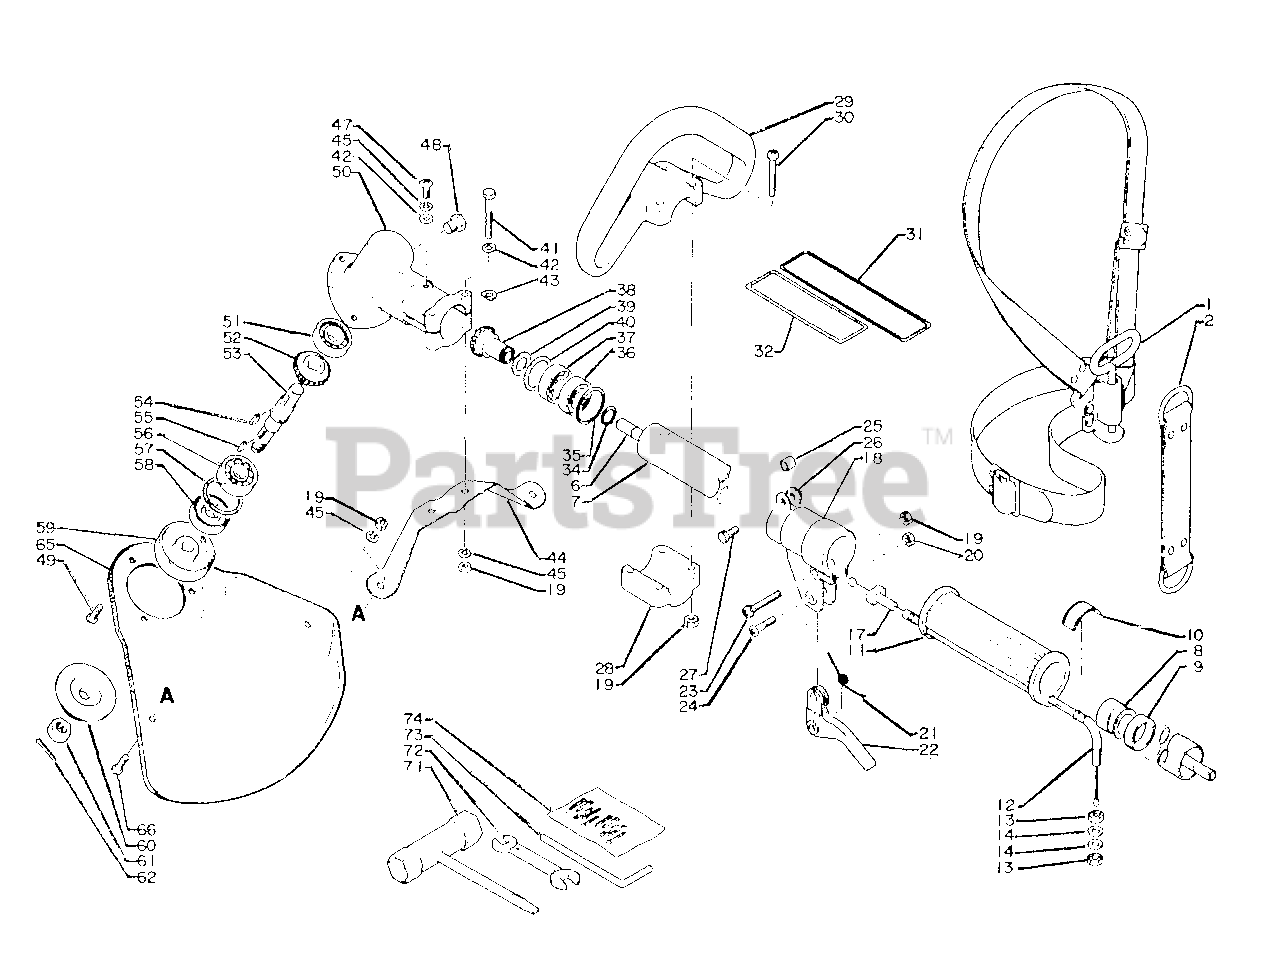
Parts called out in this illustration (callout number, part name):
1	SHOULDER STRAP ASSY
2	STRAP
6	DRIVESHAFT
7	MAIN PIPE ASSY
10	LABEL - ALIGNMENT
11	GRIP
12	CABLE, THROTTLE
13	LOCKNUT - 6
14	WASHER - 6
17	GUIDE, CABLE
18	BRACKET, TRIGGER
20	LOCKNUT - 5
21	SPRING, TRIGGER
22	TRIGGER, THROTTLE
23	SCREW - 5X30
24	SCREW - 5X30
27	BOLT - 5X18
28	BRACKET, HANDLE
29	LOOP HANDLE ASSY
30	SCREW - 5X35
31	LABEL - CAUTION
32	LABEL - CAUTION
34	RING, RETAINING - 12
35	RING, RETAINING - 28
36	BEARING, BALL - 6001
37	BEARING, BALL - 6001
38	GEAR SET
41	BOLT - 5X40
42	WASHER - 5
44	BRACKET, SHIELD
45	LOCKWASHER - 5
47	SCREW - 5X10
48	BOLT - 8X8
49	SCREW - 5X10
50	CASE, GEAR
51	BEARING, BALL - 6000
52	GEAR SET
53	DRIVESHAFT
56	BEARING, BALL - 6201
57	RING, RETAINING - 32
58	SEAL, OIL
59	ADAPTOR, BLADE - UPPER
60	ADAPTOR, BLADE - LOWER
61	NUT - 10 -- LEFT HAND
62	PIN, SPLIT - 2X22
65	SHIELD, DEBRIS - METAL
66	SCREW - 5X8
71	T-WRENCH
72	SPANNER - 8X10mm
73	LOCKING TOOL
74	PIN, SPLIT - 2X22
